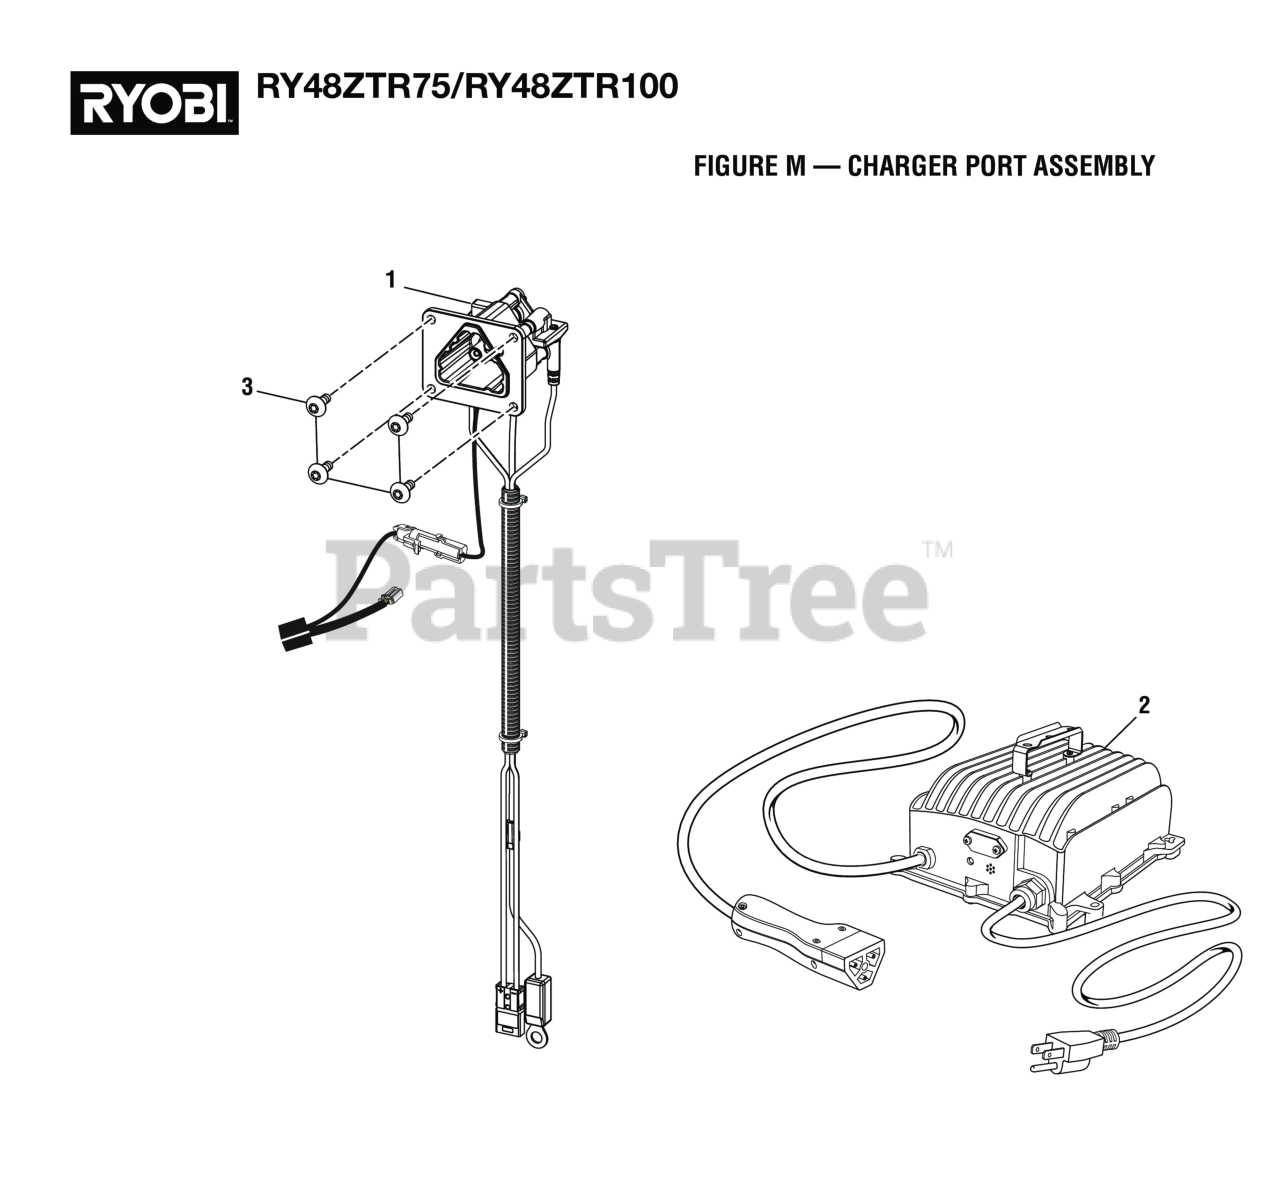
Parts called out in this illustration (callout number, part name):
1	Charger Receptacle
2	Charger
3	Screw (M6 x 10 mm, Soc. Button Hd.)
